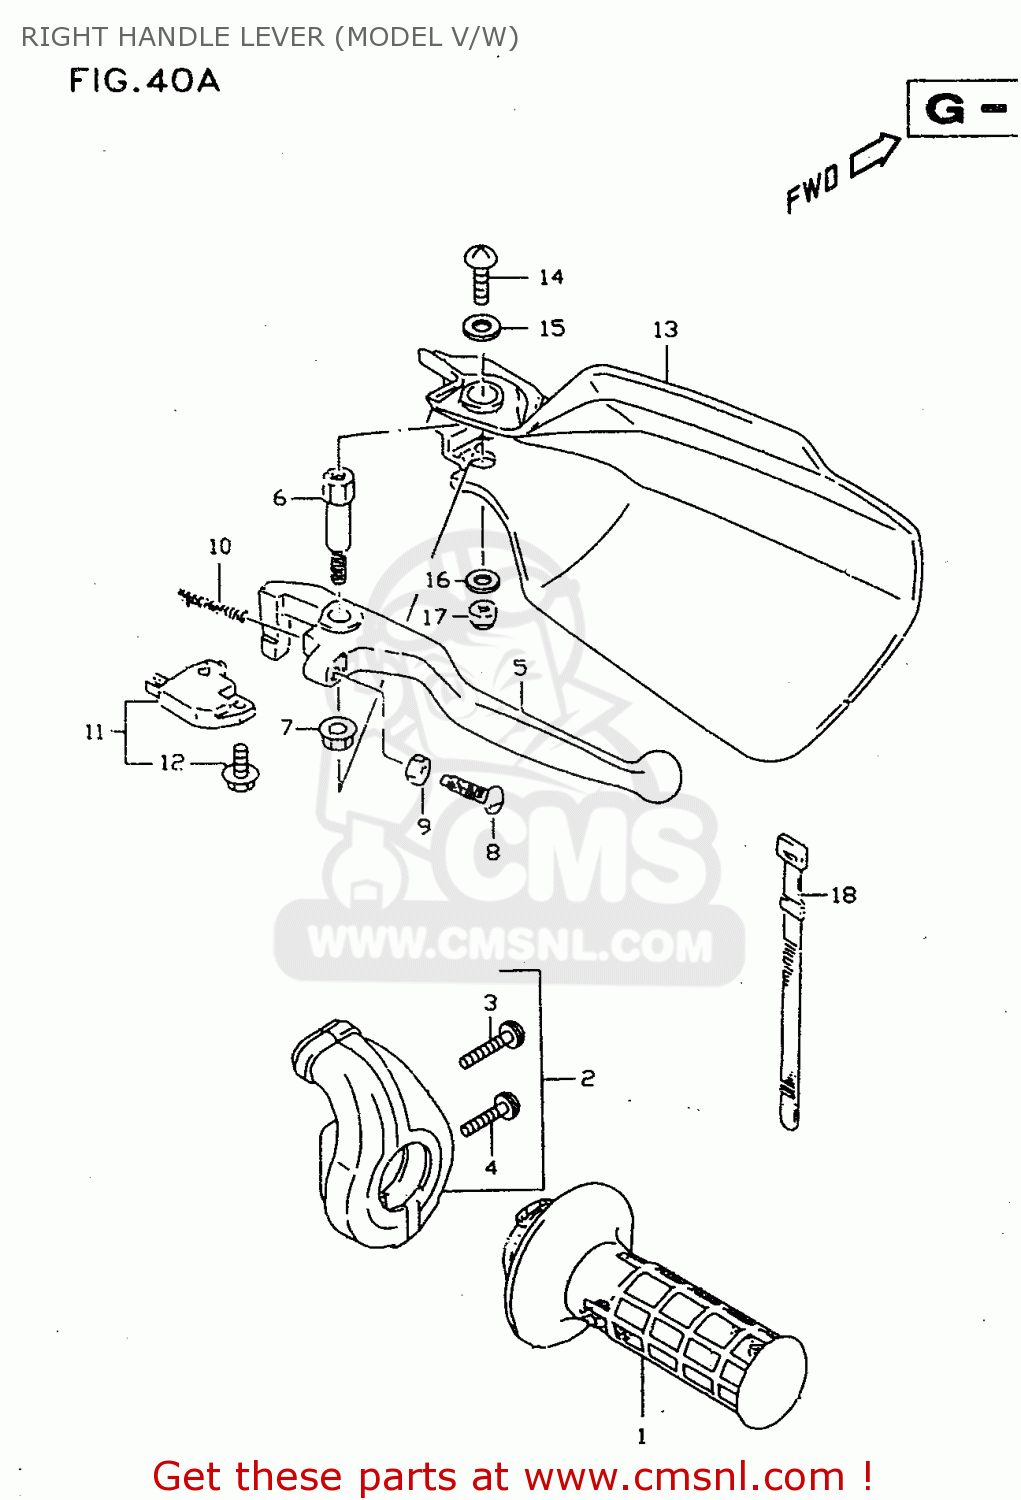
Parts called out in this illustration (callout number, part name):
1	GRIP,THROTTLE
2	CASE ASSY,THROTTLE
3	SCREW(5X25)
4	SCREW
5	LEVER,BRAKE
6	BOLT,BRAKE LEVER PIVOT
7	NUT 6MM
8	BOLT,ADJUST
9	NUT
10	SPRING,RETURN
11	SWITCH ASSEMBLY,STOP
12	SCREW
13	COVER,KNUCKLE,R
14	SCREW
15	WASHER(5.5X16X1.2)
16	WASHER(6.5X16X1.6)
17	NUT 6MM
18	CLAMP(L:120)
